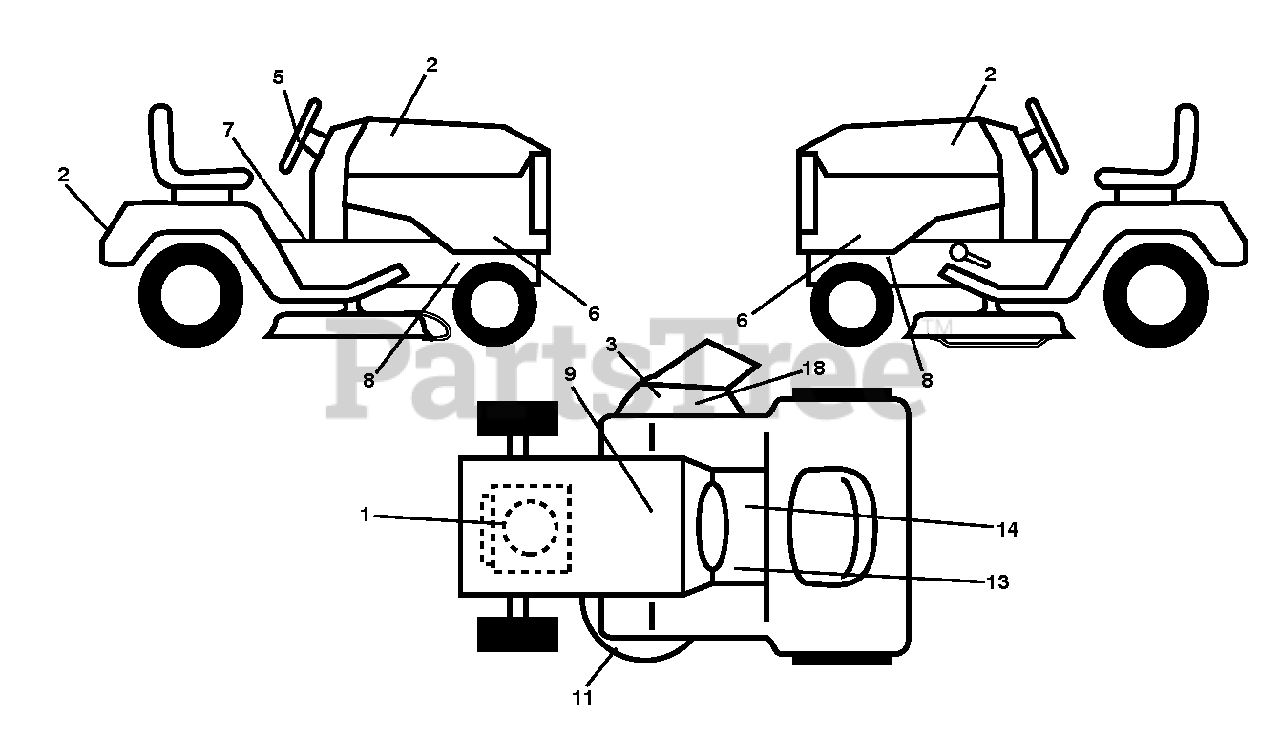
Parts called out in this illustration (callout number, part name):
1	DECAL.ENGINE.WARNING
2	DECAL, DIXON LOGO, DOMED
5	DECAL.WHEEL.STEER.DIXON
6	DECAL.PNL.SD.26/54.KAWA.DIXON
7	DECAL.READ.OWN.MAN.SYMBOL.LT
8	DECAL.CHASSIS.HOT.MUFFLER
9	DECAL BTRY SYMBOLS
11	DECAL.MOWER.SCH.48/54.PREM
13	DECAL.FNDR.SDLE.BRAKE.CLUTCH.6
14	DECAL.PARKING.BRAKE.SADDLE.LT
18	DECAL.DFLCTR.WARNNG.CTFNGR.SYM
